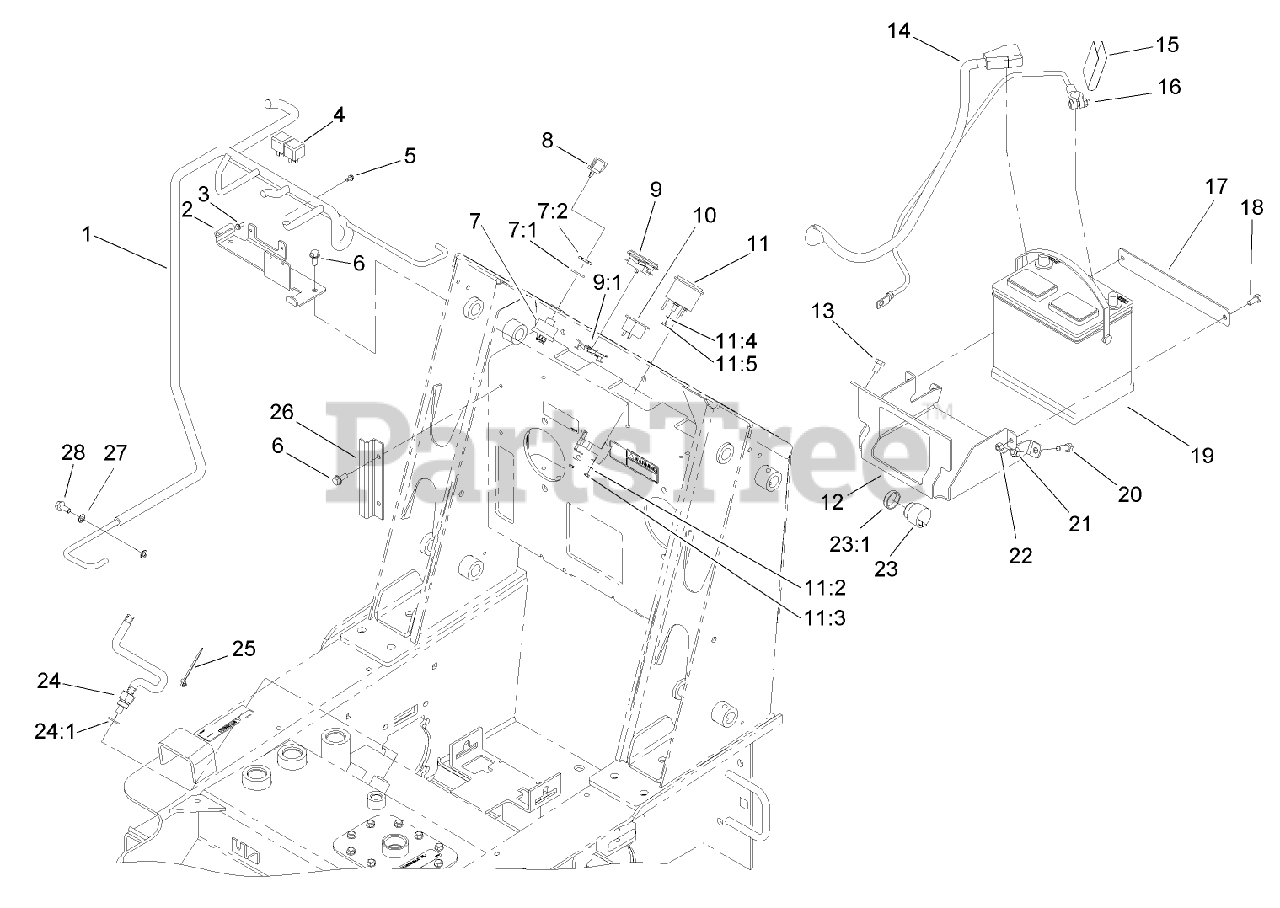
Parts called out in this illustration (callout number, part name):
1	HARNESS-WIRE
2	Fuse/Relay Bracket ASM
3	SCREW-HWH
4	RELAY
5	SCREW-HWH
6	SCREW-HWHTF
7	Key Switch ASM
7:1	WASHER-TOOTH, INTERNAL
7:2	NUT-HH
8	KEY-IGNITION
9	INDUCTIVE HOURMETER ASM
9:1	CLIP-MOUNTING
10	LIGHT-TEMP, OIL
11	GAUGE-FUEL
11:2	WASHER-LOCK, INT
11:3	NUT-HEX
11:4	WASHER-LOCK / EXT
11:5	NUT-HEX
12	TRAY-MOUNTING, BATTERY
13	SCREW-HWHTF
14	CABLE-BATTERY, POSITIVE
15	DECAL-INSTRUCTIONS, CHARGING
16	CABLE-BATTERY, NEGATIVE
17	CLAMP-BATTERY
18	SCREW-HH
19	BATTERY
20	SCREW-HH
21	NUT-LOCK, NI
22	NUT-LOCK, NI
23	AUDIO ALARM ASM
23:1	NUT-PLASTIC, KNURLED
24	SENSOR-TEMPERATURE
24:1	O-RING
25	TIE-CABLE
26	SHIELD-WIRING
27	WASHER-LOCK
28	SCREW-HHF
